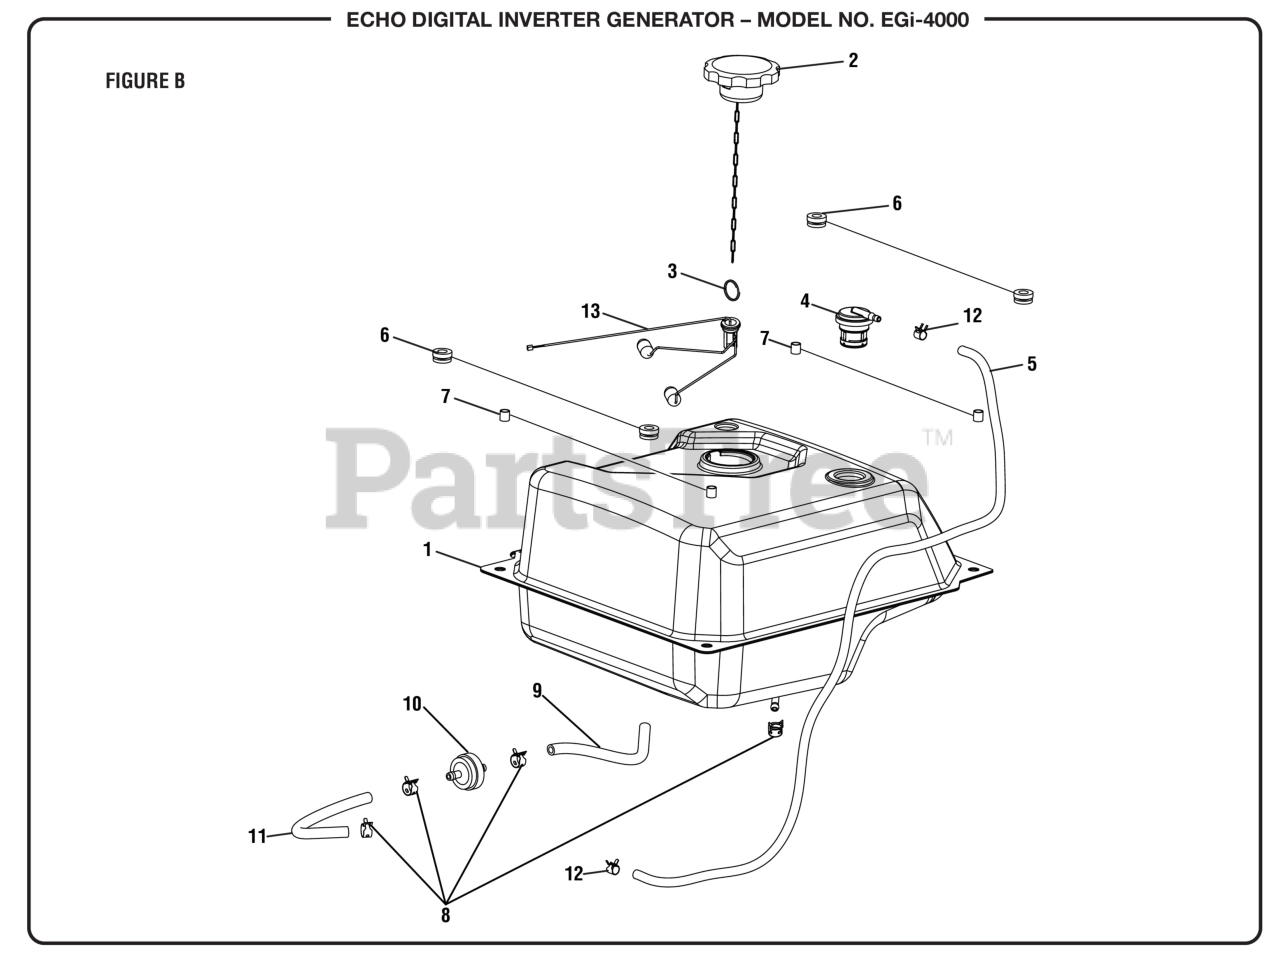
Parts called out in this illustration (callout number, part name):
1	ASSY., FUEL TANK
2	CAP, FUEL W/CHAIN
3	RING CLIP
4	VENT, VAPOR
5	HOSE, VAPOR
6	BUSHING, FUEL TANK
7	SPACER, FUEL TANK ISOLATOR
9	HOSE, FUEL
10	FILTER, FUEL
11	HOSE, FUEL
12	CLAMP, FUEL HOSE
13	SENSOR, FUEL LEVEL
